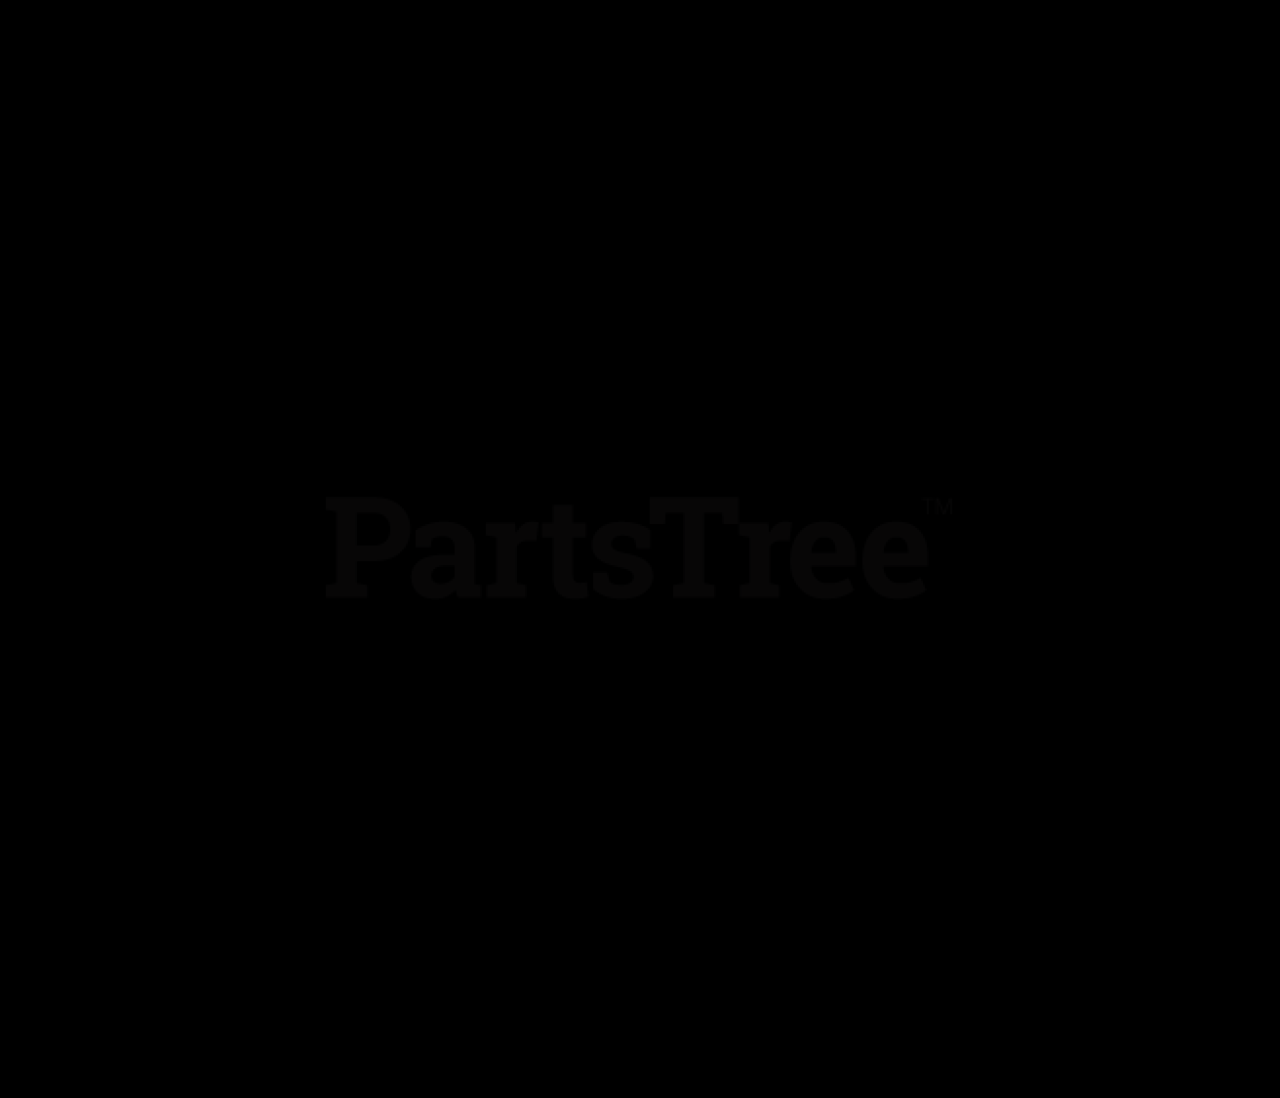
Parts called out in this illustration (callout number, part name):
1	Decal, Mower Pan Head Danger
2	Set, Decal-Common Danger/Fuel
3	Decal, Hot Surface
4	Decal, Warning
5	Decal, Instructional
6	Decal, Danger Fan
7	Decal, XDZ
8	Decal, Diesel (992215)
9	Decal, Liquid Cooled
